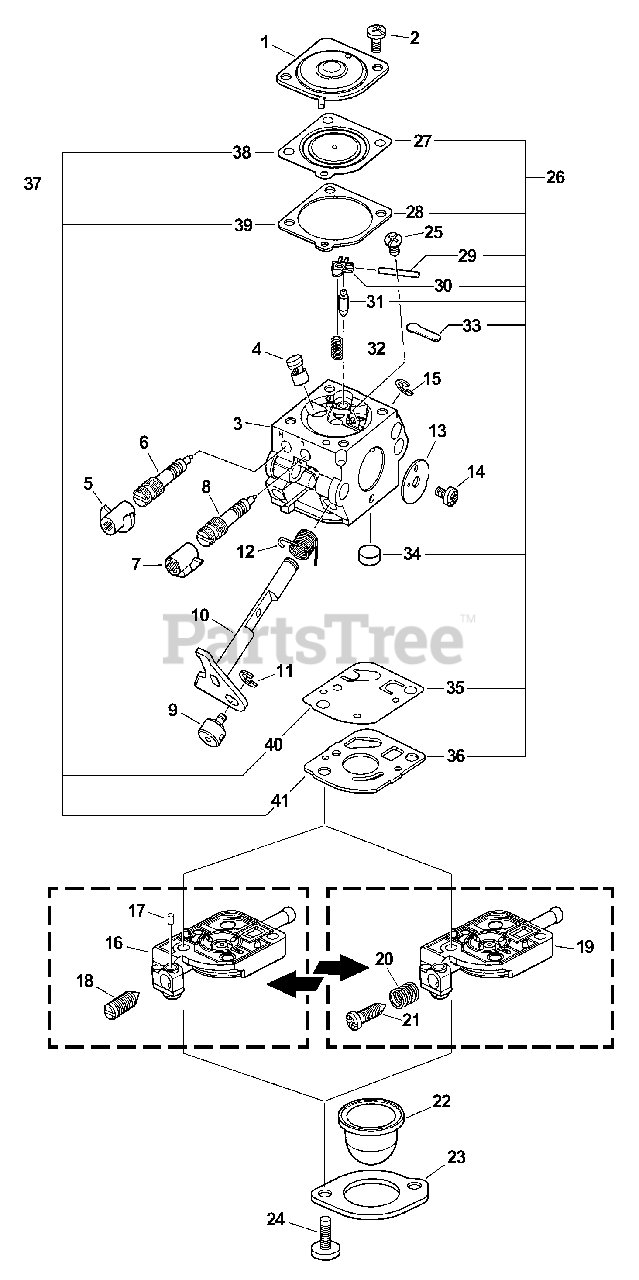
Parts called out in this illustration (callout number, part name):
1	COVER, METERING
3	BODY, CARBURETOR
4	NOZZLE, CHECK VALVE
5	CAP, LIMITER
6	NEEDLE - HIGH SPEED
7	CAP, LIMITER
8	NEEDLE - LOW SPEED
10	SHAFT, THROTTLE
11	RING, RETAINING
12	SPRING, RETURN
13	VALVE, THROTTLE
15	RING, RETAINING
16	BASE, PURGE
17	PIECE, FRICTION
18	SCREW, IDLE ADJUST
19	BASE, PURGE
20	SPRING, IDLE ADJUST
21	SCREW, IDLE ADJUST
22	BULB, PURGE
23	RETAINER, PURGE BULB
24	SCREW, RETAINER
25	SCREW, METERING LEVER PIN
26	REPAIR KIT
27	DIAPHRAGM, METERING
28	GASKET, METERING
29	PIN, METERING LEVER
30	LEVER, METERING
31	VALVE, INLET NEEDLE
32	SPRING, METERING LEVER
33	PLUG, WELCH
34	STRAINER
35	DIAPHRAGM, PUMP
36	GASKET, PUMP
37	DIAPHRAGM/GASKET KIT
38	DIAPHRAGM, METERING
39	GASKET, METERING
40	DIAPHRAGM, PUMP
41	GASKET, PUMP
